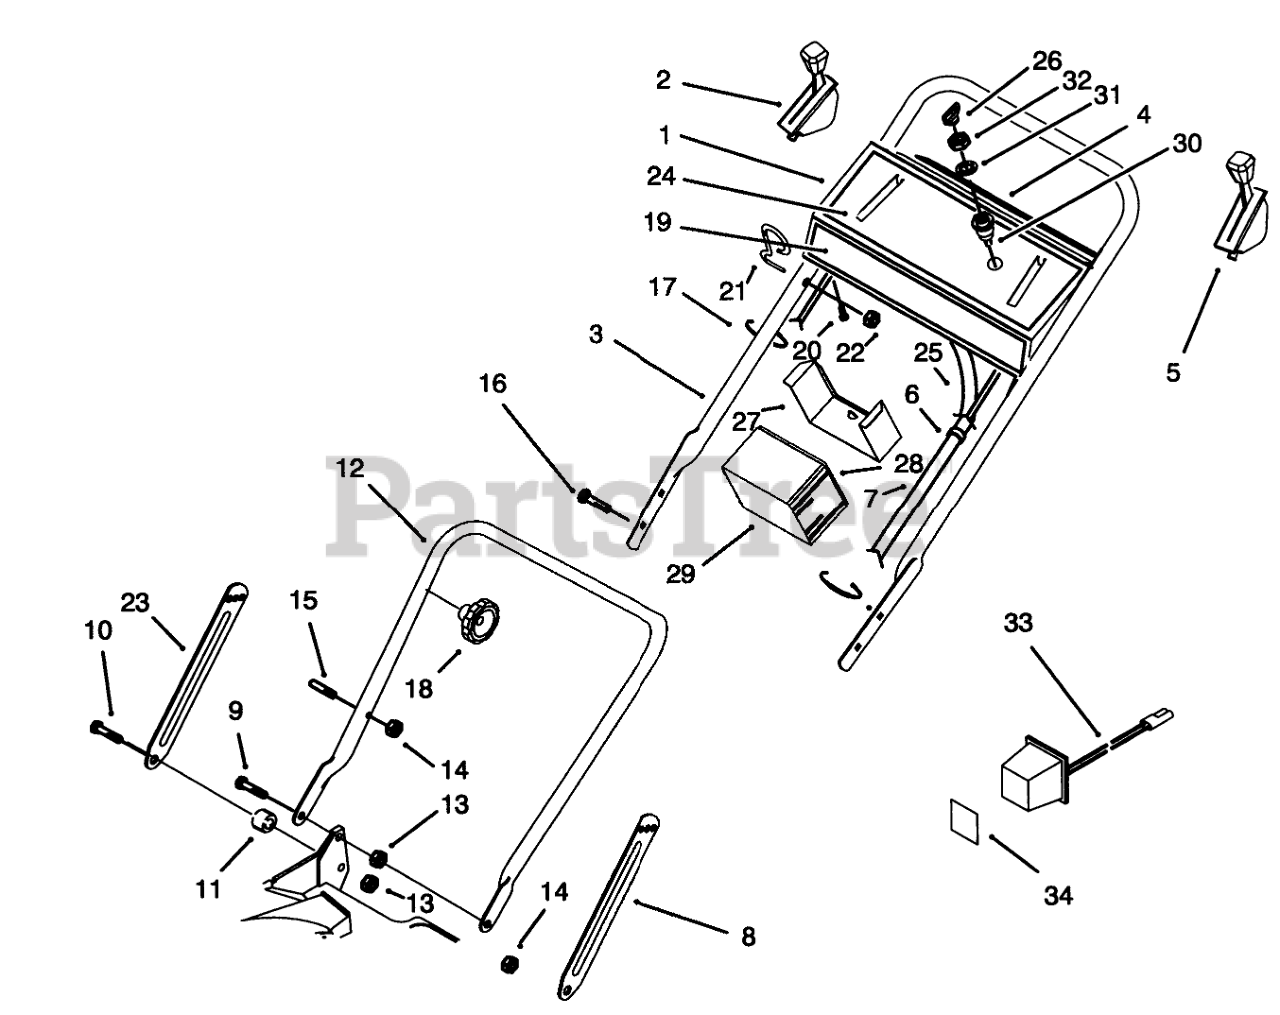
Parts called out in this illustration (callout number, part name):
1	Panel-Control (Incl. Ref. #4,19, & 24)
2	CONTROL-SPEED, GROUND
3	Handle-Upper
4	DECAL-PANEL, DANGER
5	THROTTLE CONTROL
6	FITTING-RING
7	CONTROL CABLE COVER
8	Latch-Handle
9	SCREW-SHOULDER
10	SCREW-SHOULDER
11	SPACER
12	LOWER HANDLE ASM
13	NUT-LOCK, NI
14	NUT-LOCK, NI
15	HANDLE PIN
16	SCREW-HANDLE
17	TIE-CABLE
19	DECAL - FRT PANEL
20	10-16X1/2 SHWH SCREW
21	GUIDE-ROPE
22	NUT-LOCK, NI
23	Latch-Handle
24	DECAL - INSTRUCTION
25	WIRING HARNESS
26	KEY-IGNITION
27	Retainer-Battery
28	DECAL - BATTERY
29	BATTERY ASSEMBLY
30	Switch-Starter (Incl. Ref. #31 & 32)
31	WASHER-TOOTH, INTERNAL
32	NUT-HH
33	Charger-Battery
34	DECAL - CAUTION F/W
